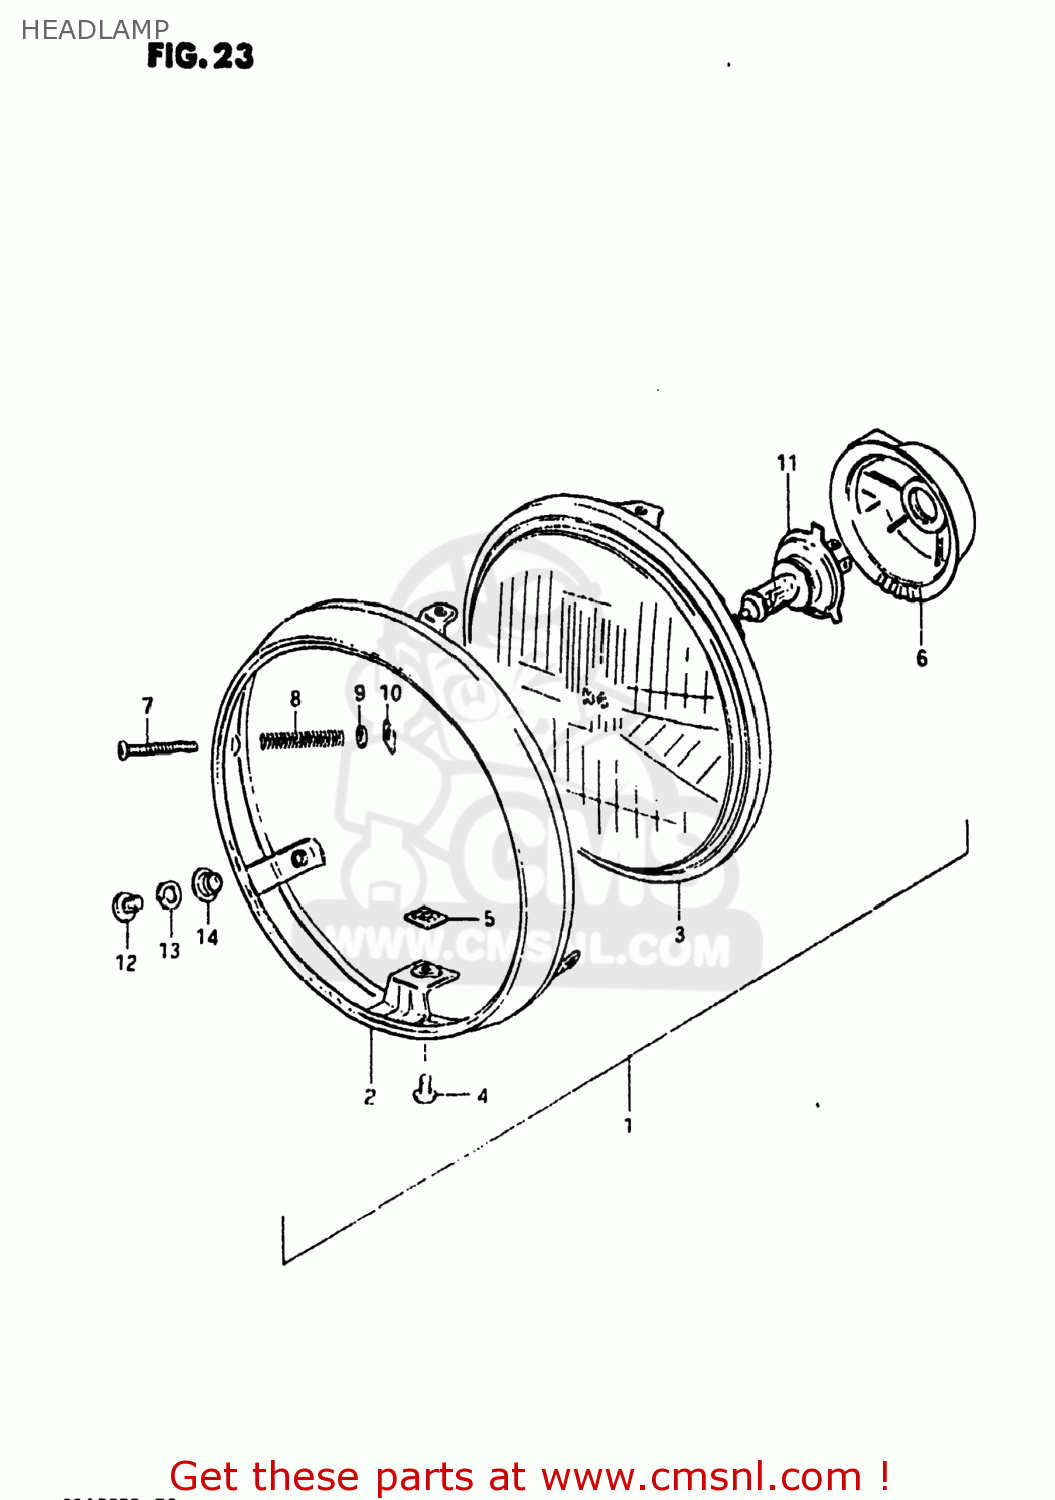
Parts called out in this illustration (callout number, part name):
1	HEADLAMP ASSEMBLY
2	RIM
3	LAMP UNIT
4	SCREW
5	NUT,ADJUSTING
6	COVER,SOCKET
7	SCREW,HEADLAMP ADJUST
8	SPRING
9	WASHER
10	NUT,HEADLAMP ADJUSTER
11	BULB(12V60/55W,H4)
12	SCREW
13	WASHER,LOCK
14	WASHER
